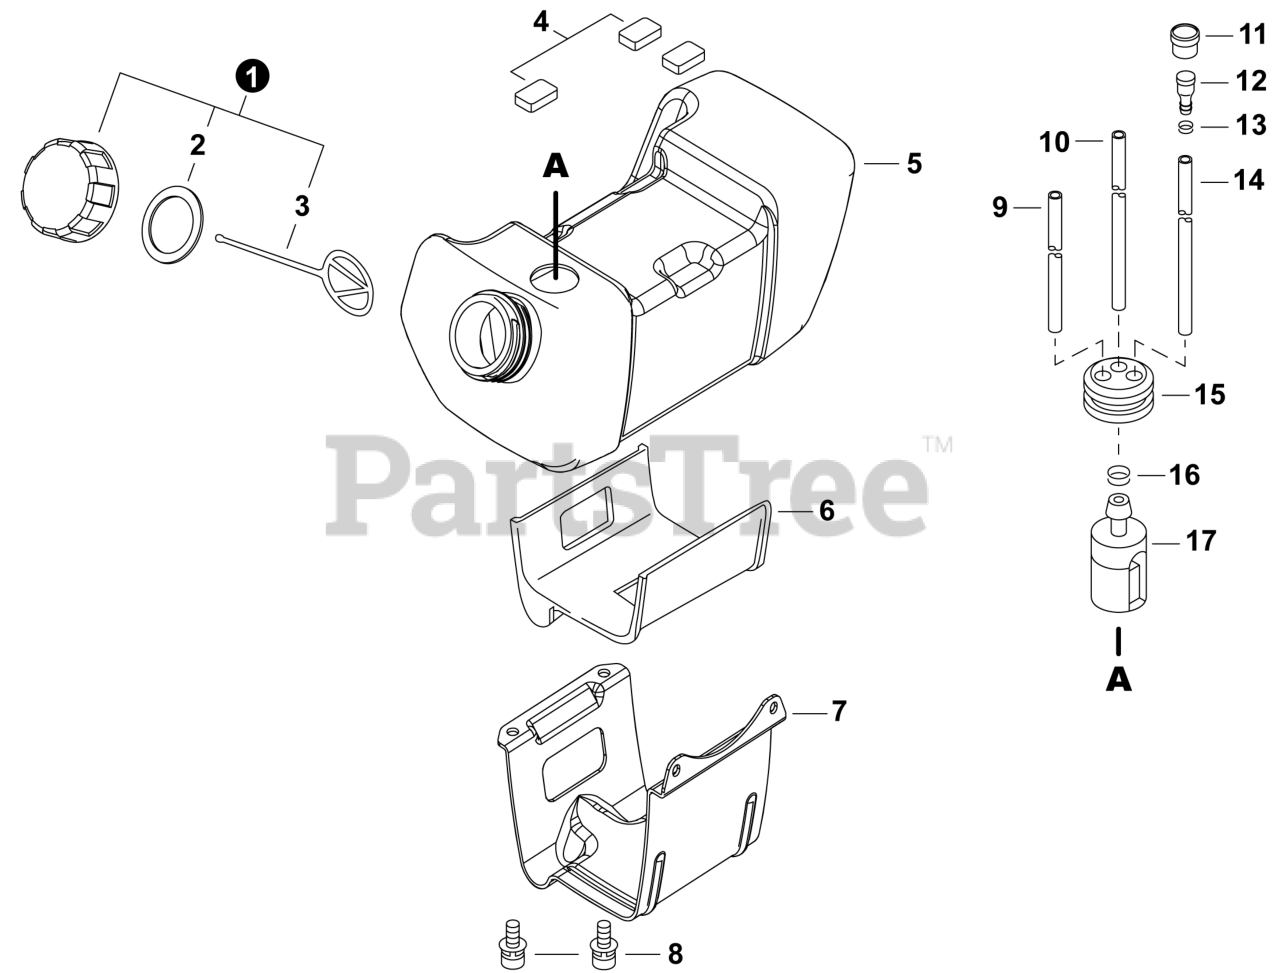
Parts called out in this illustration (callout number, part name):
1	CAP ASSY, FUEL
2	GASKET, FUEL CAP
3	CONNECTOR, CAP L= 100 MM
5	TANK, FUEL
6	CUSHION, FUEL TANK
7	BRACKET, FUEL TANK
8	BOLT 5x14
9	PIPE, FUEL 3x6x80 YELLOW
10	PIPE, FUEL 3x5x210 BLACK
11	HOLDER, VENT
12	VENT ASSY
13	CLIP 6.5 MM
14	PIPE, FUEL 3x6x30 BLACK
15	GROMMET, FUEL
17	FILTER, FUEL
